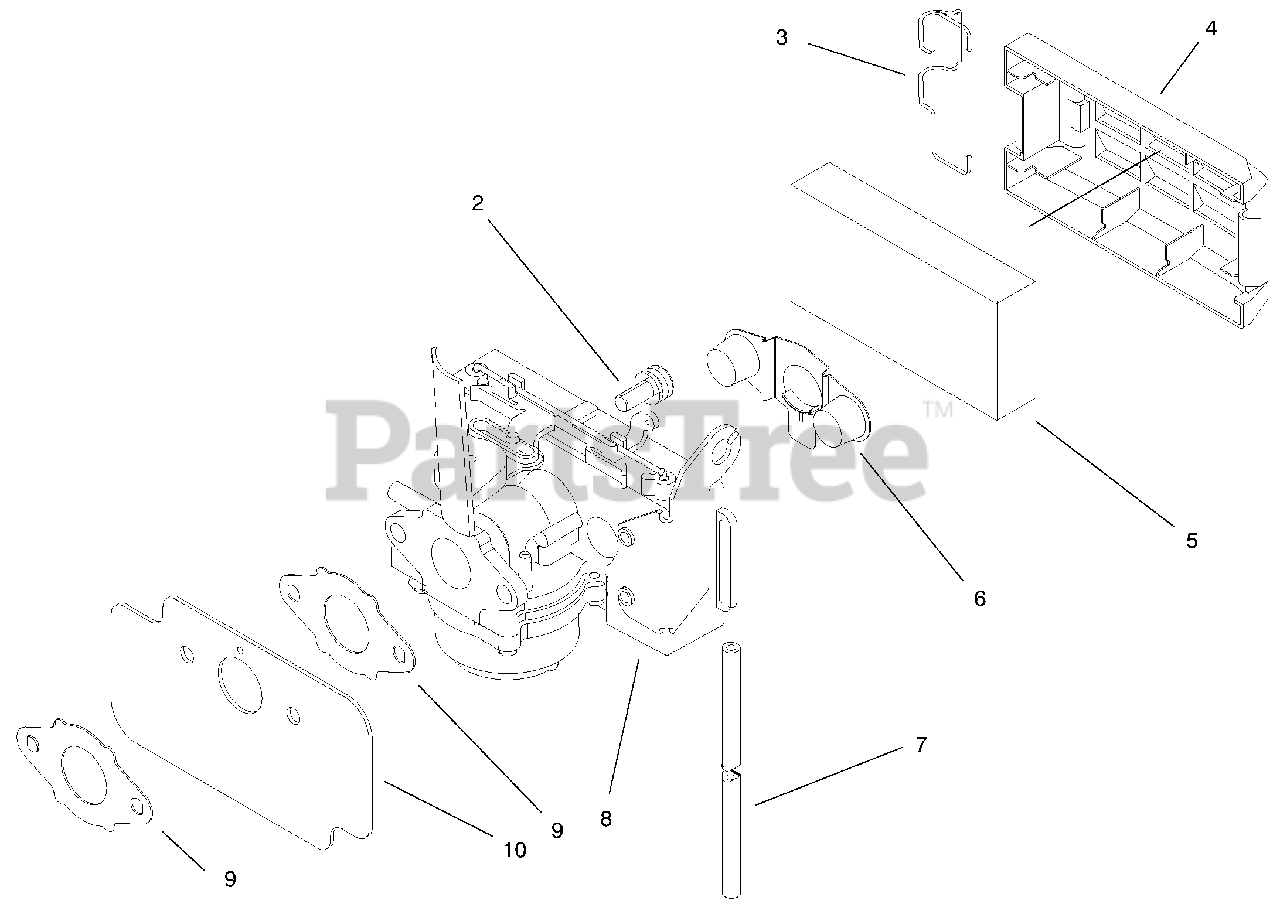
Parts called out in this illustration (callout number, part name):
3	Retainer-Filter
4	Cover-Air Cleaner
5	Element-Filter Air
6	Shield-Fuel
7	Hose-Primer
8	Carburetor Assembly (Incl. Ref. #9)
9	Gasket-Carburetor
10	Shield-Carburetor
